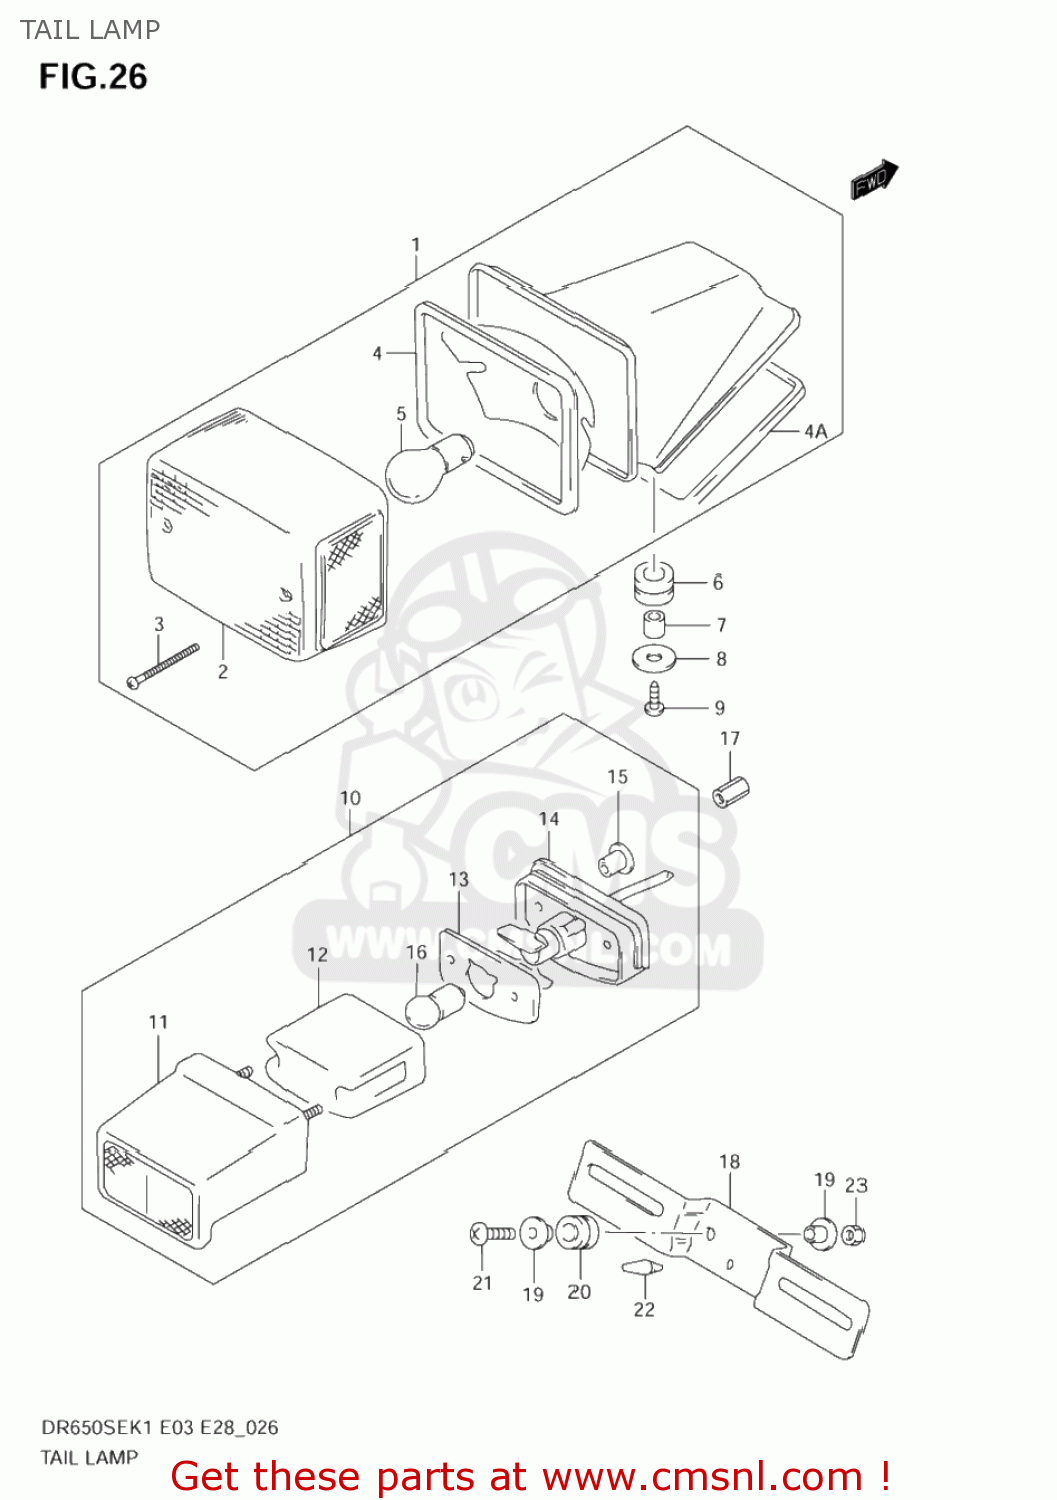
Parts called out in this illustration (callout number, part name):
1	LAMP ASSY,RR COMBINATION
2	LENS,TAIL LAMP
3	SCREW(4X45)
4	GASKET,LENS (NAS)
4A	GASKET (NAS)
5	BULB(12V21/5W)
6	CUSHION
7	SPACER(6.1X8X9.5)
8	WASHER(6.5X20X1.6)
9	SCREW
10	LAMP ASSY,LICENSE
11	COVER,LICENSE
12	LENS
13	GASKET,LICENSE LAMP (NAS)
14	CUSHION
15	SPACER
16	BULB(12V5W,BF150-40160A)
17	NUT
18	BRACKET,LICENSE PLATE
19	WASHER
20	CUSHION
21	SCREW
22	CUSHION
23	NUT 6MM
